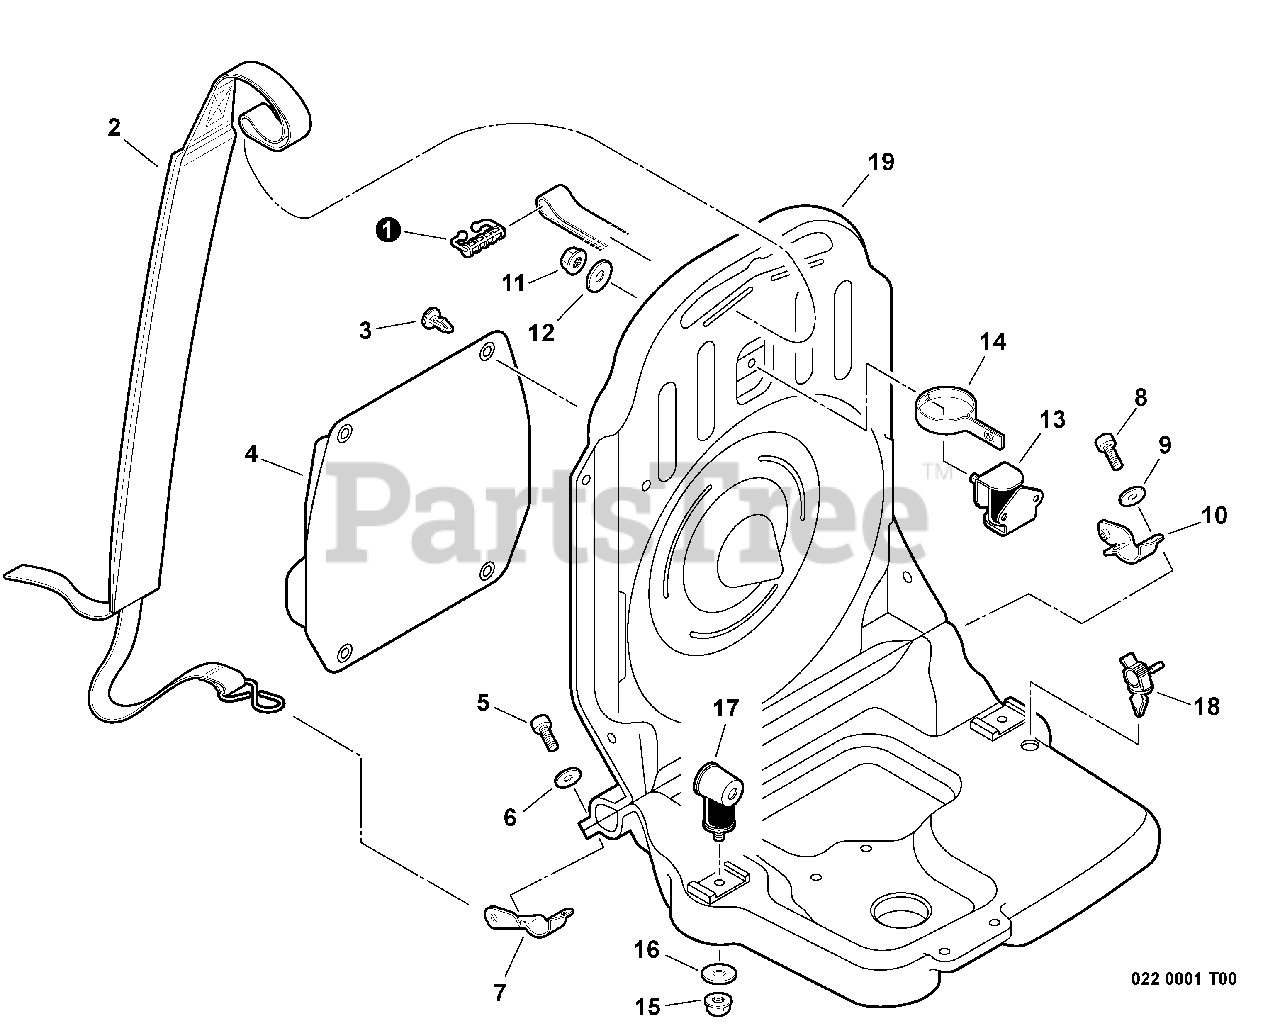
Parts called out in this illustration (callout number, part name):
1	RETAINER, HARNESS
2	BACKPACK STRAP ASSY
4	CUSHION, BACKPACK
5	SCREW - 5X20
6	WASHER - 5
7	CONNECTOR, STRAP - LEFT
8	SCREW - 5X20
9	WASHER - 5
10	CONNECTOR, STRAP - RIGHT
11	NUT - 5 -- FLANGE
12	WASHER - 5
14	RETAINER
15	NUT - 5 -- FLANGE
16	WASHER - 5
17	CUSHION
18	CLIP, CABLE
19	FRAME, BACKPACK
